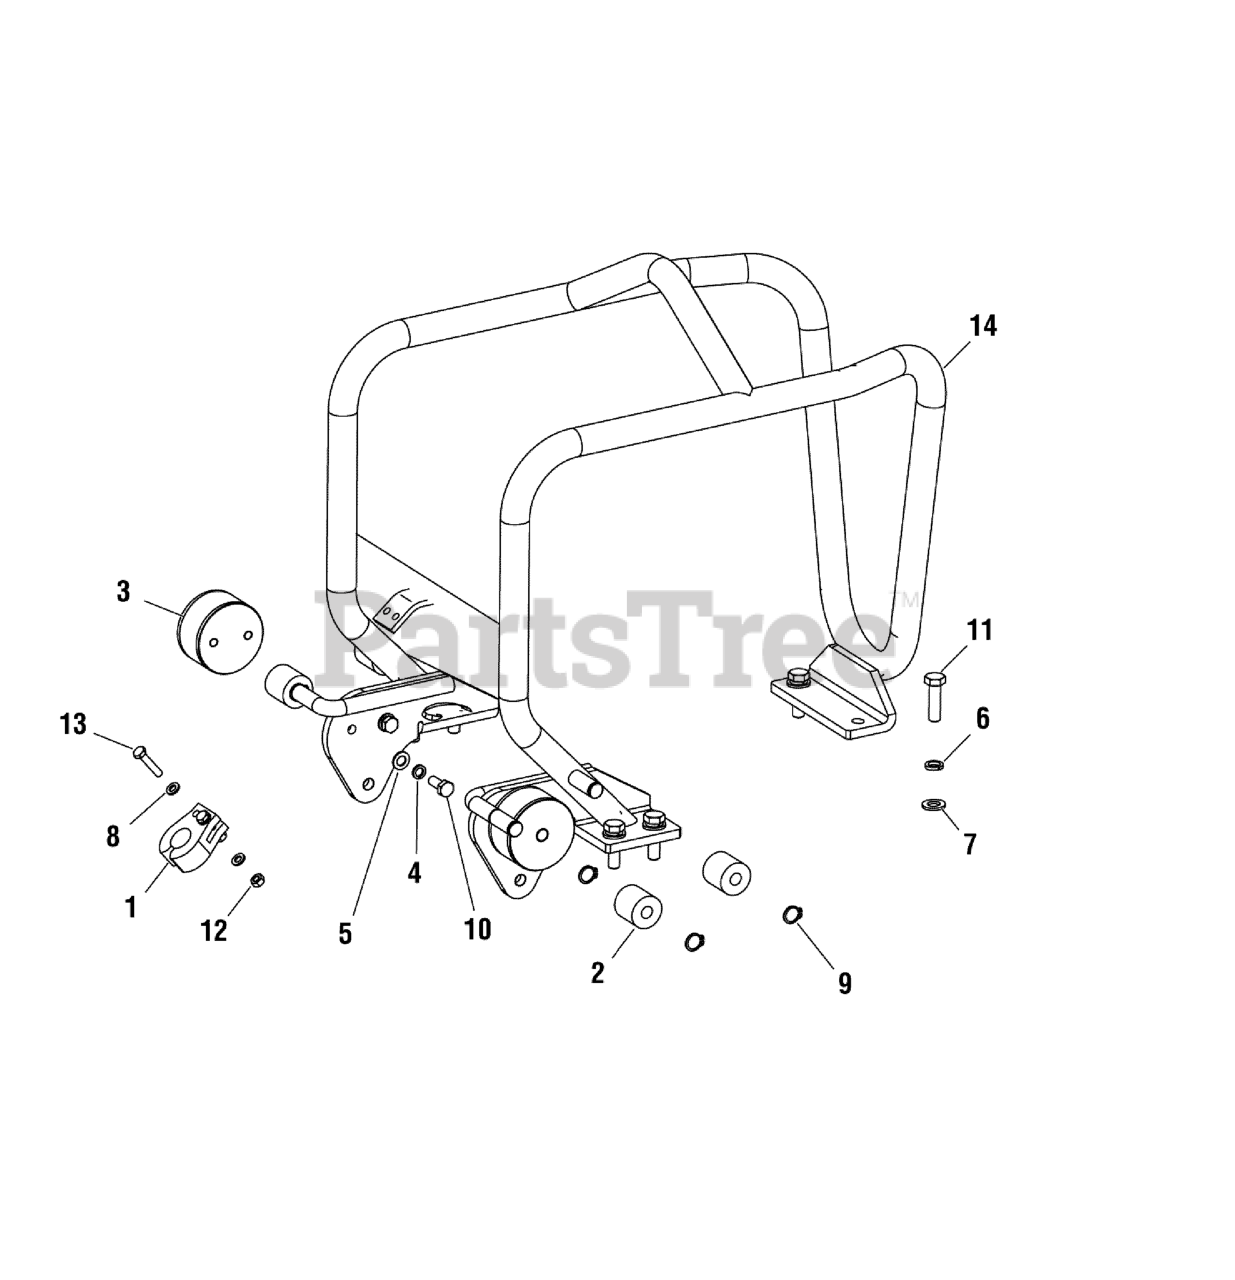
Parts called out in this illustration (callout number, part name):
1	CLIP, Rubber
2	COLLAR, Rubber
3	VIBRATION MOUNT, Rubber
4	WASHER, Spring, 8
5	WASHER, Flat, 8
6	WASHER, Spring, 10
7	WASHER, Flat, 10
8	WASHER, Flat, 6
9	CIRCLIP
10	BOLT, Hex, M8 x 20
11	BOLT, Hex, M10 x 35
12	NUT, Hex, M6
13	BOLT, Hex, M6 x 30
14	GUARD HOOK
